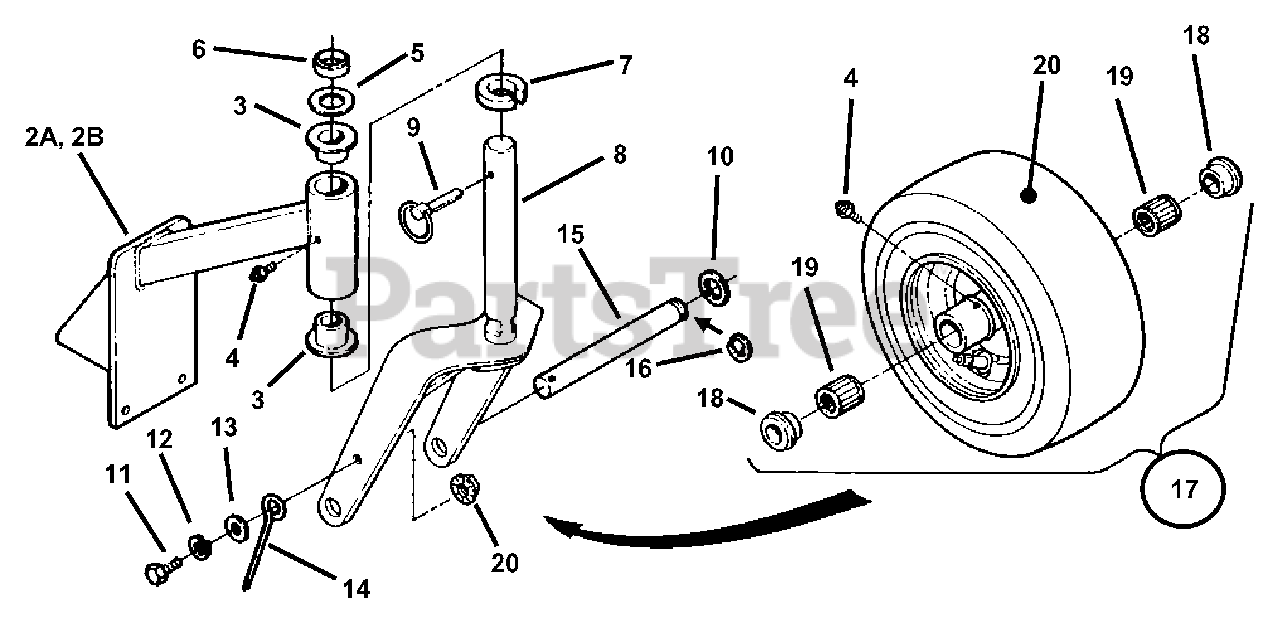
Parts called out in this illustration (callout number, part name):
1A	ASSEMBLY, Caster (36" Deck only)
1B	ASSEMBLY, Caster (48", 52" & 61" Decks)
2A	SUPPORT, Caster (36" Deck only)
2B	SUPPORT, Caster (48", 52" & 61" Decks)
3	BUSHING, Flange (2)
4	FITTING, 1/4-28, Straight Lube
5	BUSHING, Machinery, 1"
6	SPACER, 1" x 1 3/8 x .30" (PM)
7	SPACER, Caster
8	WELDMENT, Caster Yoke
9	PIN, 7/16" Lynch
10	BUSHING, Machinery, 3/4"
11	SCREW, 3/8-16 x 7/8", Hex Head, Grade 5
12	WASHER, 3/8" Split Lock
13	WASHER, 3/8" Flat
14	MOUNT, caster Axle
15	AXLE, Caster
16	RING, 3/4" External Retaining
17	ASSEMBLY, Wheel & Tire
18	BEARING, 3/4" Flange
19	BEARING, 3/4" x 1" Roller
20	TIRE, 4-Ply Smooth Tread
